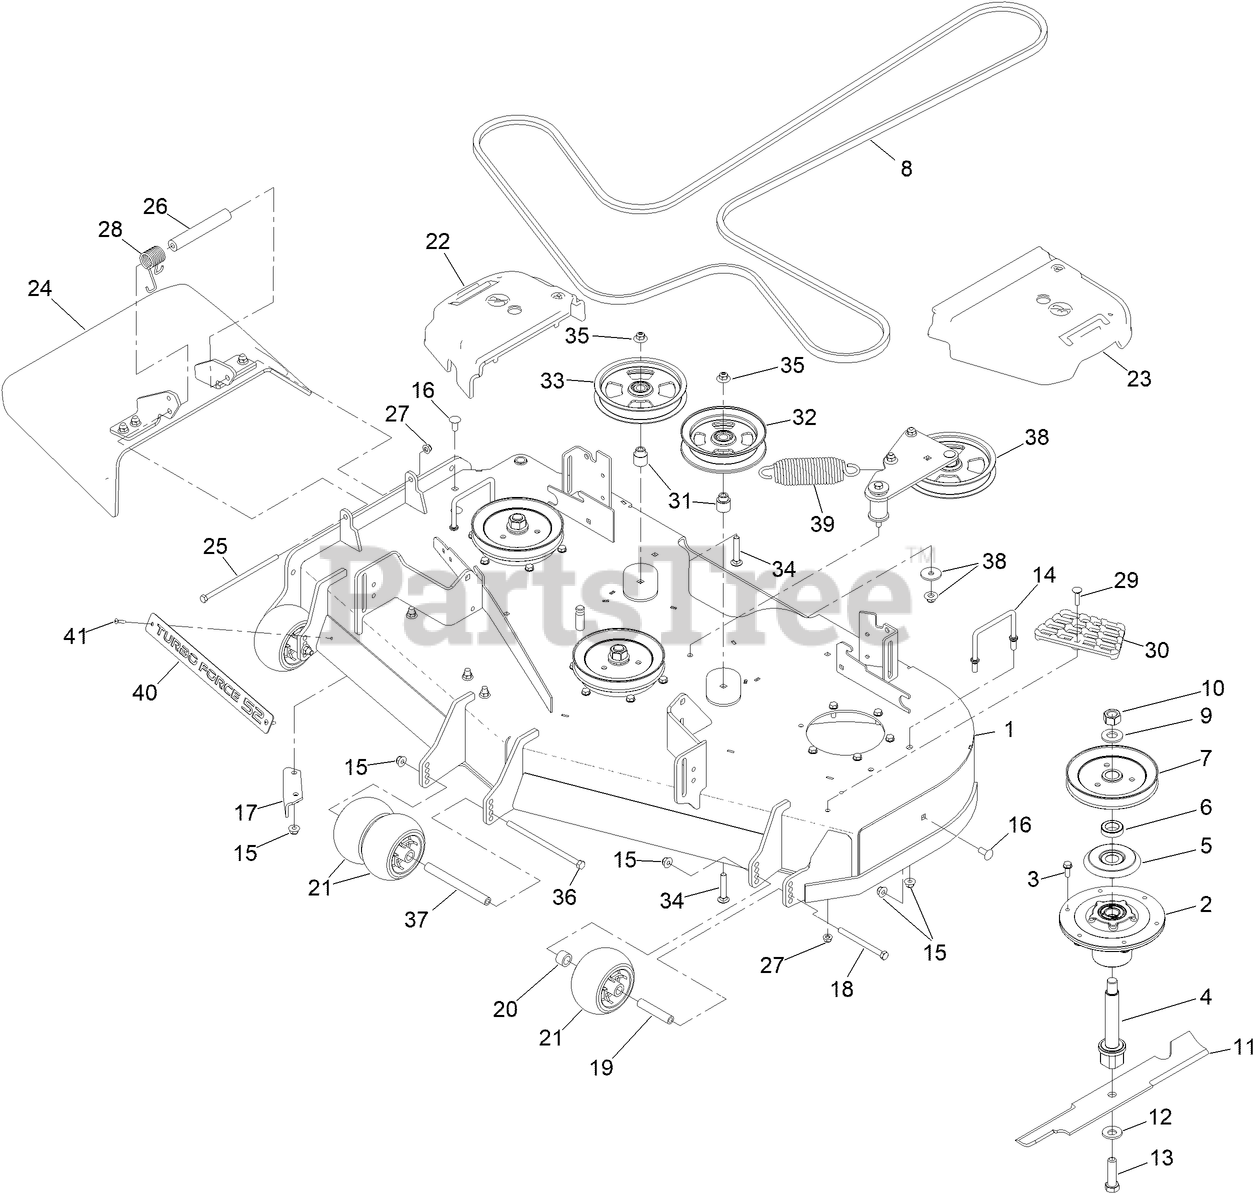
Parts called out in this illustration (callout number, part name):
1	DECK DECAL ASM
2	SPINDLE ASM
3	SCREW-TAPTITE
4	SHAFT-SPINDLE
5	SHIELD-BEARING
6	SPACER-PULLEY
7	SHEAVE-BLADE DRIVE 6.50
8	BELT-V
9	WASHER
10	NUT-HEX
11	BLADE-ROTARY, 18.0IN (HI FLOW)
12	WASHER-BELLEVILLE
13	SCREW-BLADE
14	WIREFORM-COVER
15	NUT-HF, NI
16	SCREW-CARR
17	BAFFLE-DISCHARGE
18	SCREW-HH
19	TUBE-SHAFTING
20	TUBE-SPACER
21	ROLLER-SCALP, ANTI
22	COVER-BELT, RH
23	COVER-BELT, LH
24	RUBBER DEFLECTOR ASM
25	SCREW-HH
26	SPACER
27	NUT-HF, NI
28	SPRING-TORSION
29	SCREW-CARR
30	STEP-DECK
31	BUSHING, IDLER
32	PULLEY-IDLER, FLAT
33	PULLEY-IDLER, FLAT
34	SCREW-CARR
35	NUT-FLANGE, NI
36	SCREW-HH
37	SPACER-WHEEL
38	IDLER ARM ASM
39	SPRING-EXTENSION
40	PLATE-TURBO FORCE [BLACK]
41	RIVET-TRIFOLD
